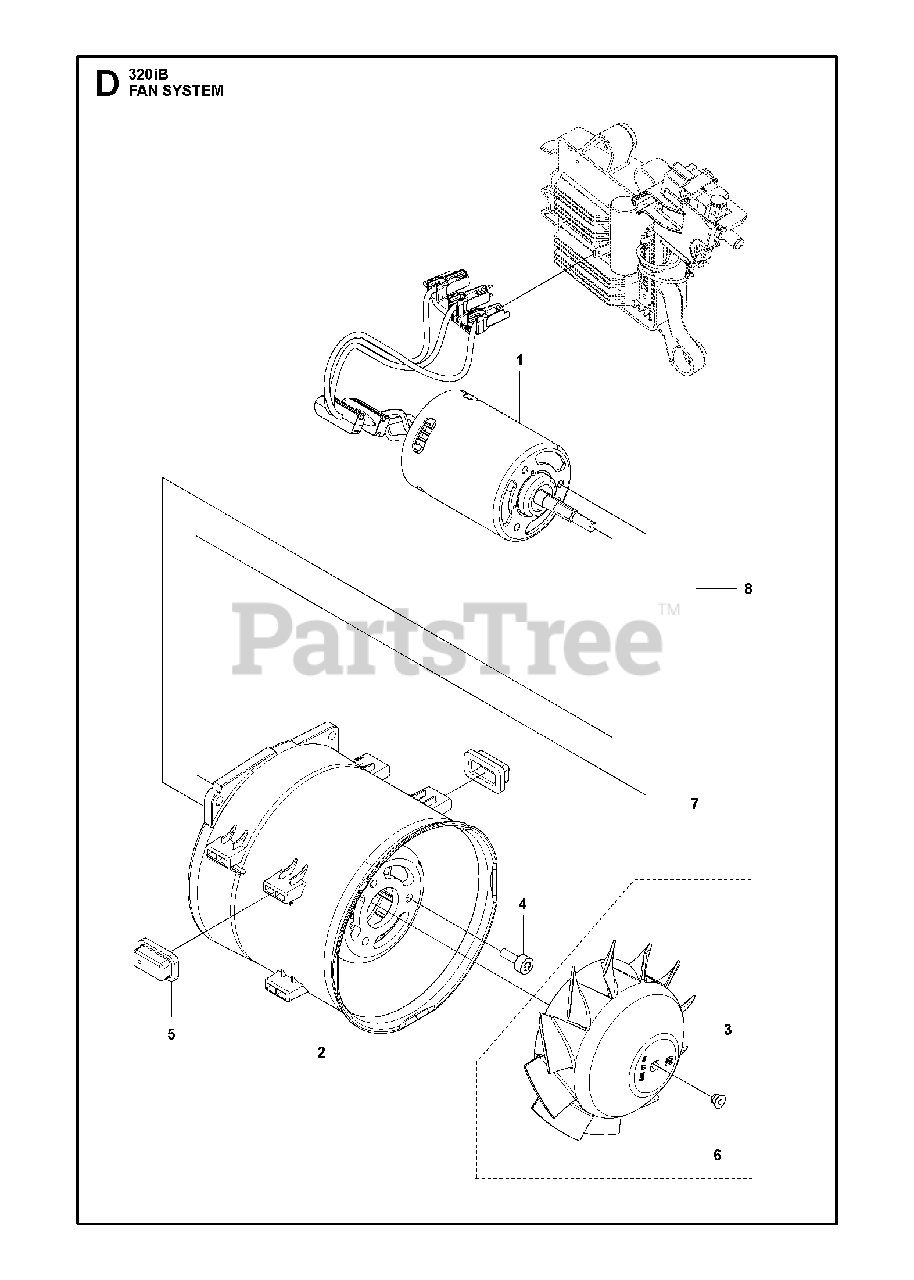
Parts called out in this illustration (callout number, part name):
1	MOTOR ASSY BLDC
2	STATOR FAN B2
3	ROTOR FAN
6	LOCKING NUT
7	ROTOR SPARE PART KIT 320IB
8	MOTOR ASSY SPARE PARTS KIT 320
